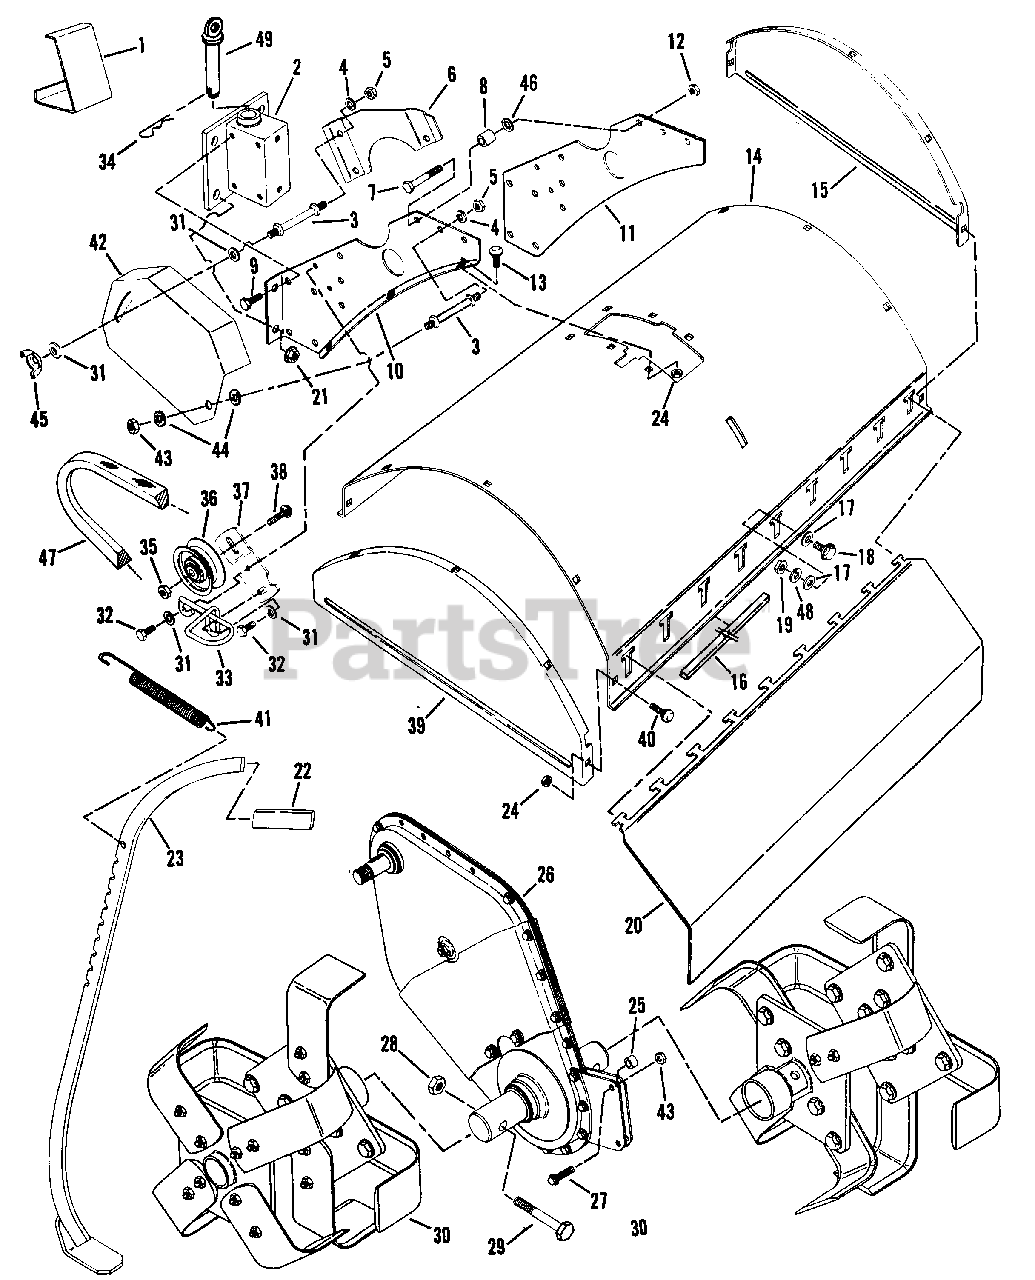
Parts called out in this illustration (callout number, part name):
1	(NLA) SPACER
2	BRACKET, Mounting
3	(NLA) STUD
4	WASHER, 5/16 Split Lock
5	NUT, 5/16-18 Hex
6	(NLA) SHIELD
7	SCREW, 5/16-24 x 2 1/2" Hex Head Cap (Gr.8)
8	SPACER, .625 OD x .388 ID x .801 Long
9	SCREW, 3/8-16 x 1/2" Self Tapping (8HP)
10	BRACKET, Mtg. Left (8HP)
10	BRACKET, Mtg. Left (5HP)
11	BRACKET, Mtg. Right (8HP)
11	BRACKET, Mtg. Right (5HP)
12	NUT, 5/16-24 Hex Lock
13	BOLT, 5/16-18 x 5/8" Short Neck Carriage
14	COVER, TINE
15	PLATE, Right Side
16	(NLA) MOULDING, Trim
17	WASHER, 3/8" Flat
18	SCREW, 3/8-16 x 3/4" Hex Head Cap (Gr.2)
19	NUT, 3/8-16 Hex
20	GUARD, Splash
21	NUT, 3/8-16 Flange Lock (5HP only)
22	GRIP, Depth Bar
23	STRUCTURE, Depth Bar
24	NUT, 5/16-18 Hex Flange Lock
25	SPACER, .5 OD x .33 ID x .4 Long
26	ASSEMBLY, Tiller Chain Case
27	SCREW, 5/16-18 x 1" Hex Head Cap
28	NUT, 3/8-24 Hex Center Lock
29	BOLT, 3/8-24 x 2 1/4" Shear
30	ASSEMBLY, Tine 13" (8HP)(See Tine Assembly Group)
30	ASSEMBLY, Tine 11.5" (5HP)(See Tine Assembly Group)
31	WASHER, 5/16 Flat (3)
32	SCREW, 5/16-18 x 1" Self Tapping
33	FINGER, Belt
34	PIN, Hair 2.25" (8HP)
35	NUT, 5/16-24 Hex Center Lock
36	IDLER, Flat 2.5" OD .375" ID
37	ARM, idler
38	BOLT, 5/16-18 x 1-3/4" Carriage (Gr.5)
39	PLATE, Left Side
40	BOLT, 5/16-18 x 1/2" Short Neck Carriage (Gr.5)
41	SPRING
42	COVER, Belt
43	NUT, 5/16-18 Hex Lock
44	WASHER, Seal
45	NUT, 5/16-18 Lock Wing
46	RETAINER, Bolt 5/16"
47	V-BELT, 4 L x 62.38" Effective Length - Kevlar
48	WASHER, 3/8 Split Lock
49	PIN, Clevis 3/4 x 6.062 (8HP)
